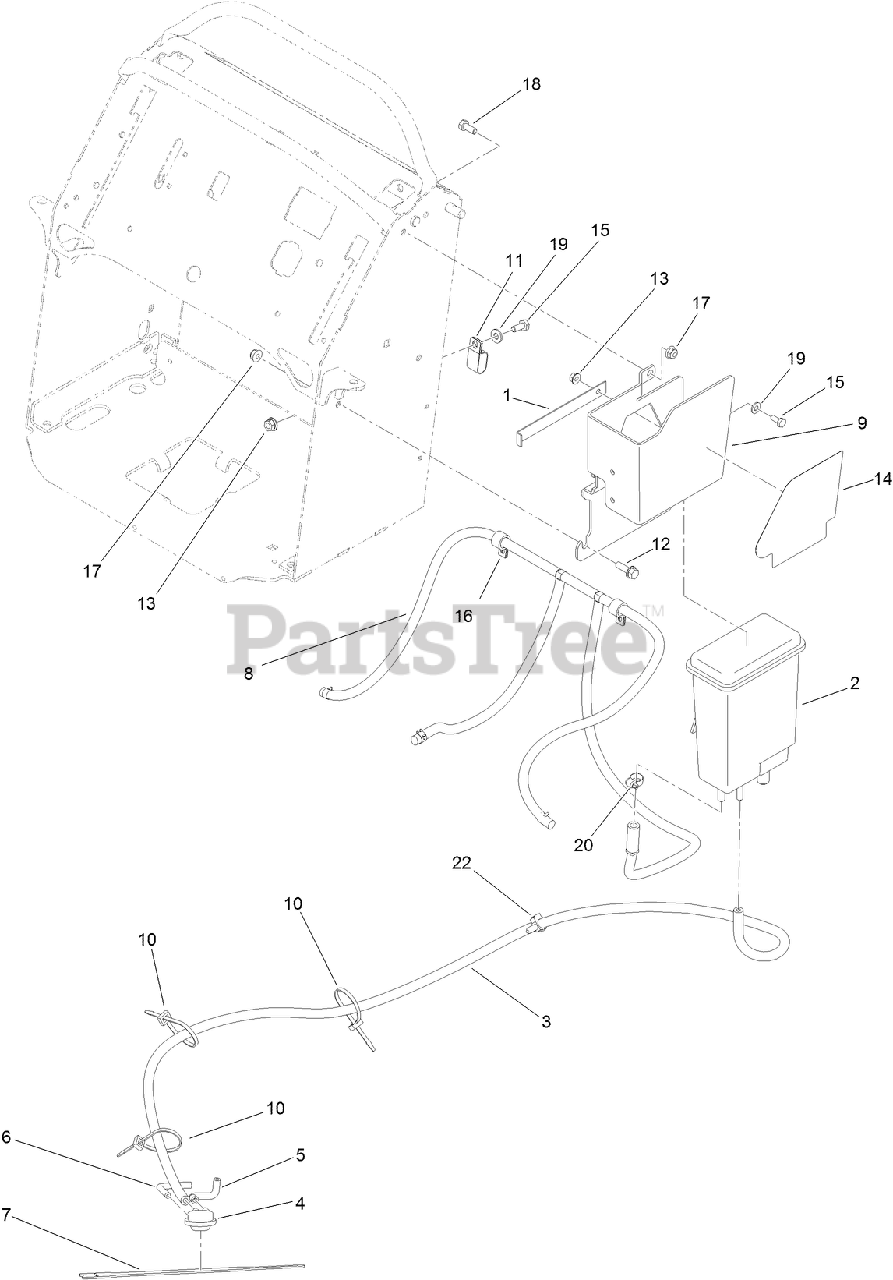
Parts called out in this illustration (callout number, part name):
1	PLATE-LOC
2	CANISTER-CARBON, 1200CC
3	HOSE-FUEL
4	VALVE-CONTROL, VACUUM
5	HOSE-VENT, FORMED
6	HOSE-VENT, FORMED
7	STRAP-VELCRO, CABLE TIE
8	VENT HOSE ASM
9	PLATE- ADAPTER
10	TIE-CABLE
11	CLAMP-TUBE, DOUBLE
12	SCREW-HHF
13	NUT-HHF
14	DECAL-SERVICE/SPARK ARREST
15	SCREW-HH
16	CLAMP-CABLE
17	NUT-HF, NI
18	SCREW-HH
19	WASHER-FLAT
20	CLAMP-WORM
22	CLIP-HARNESS
